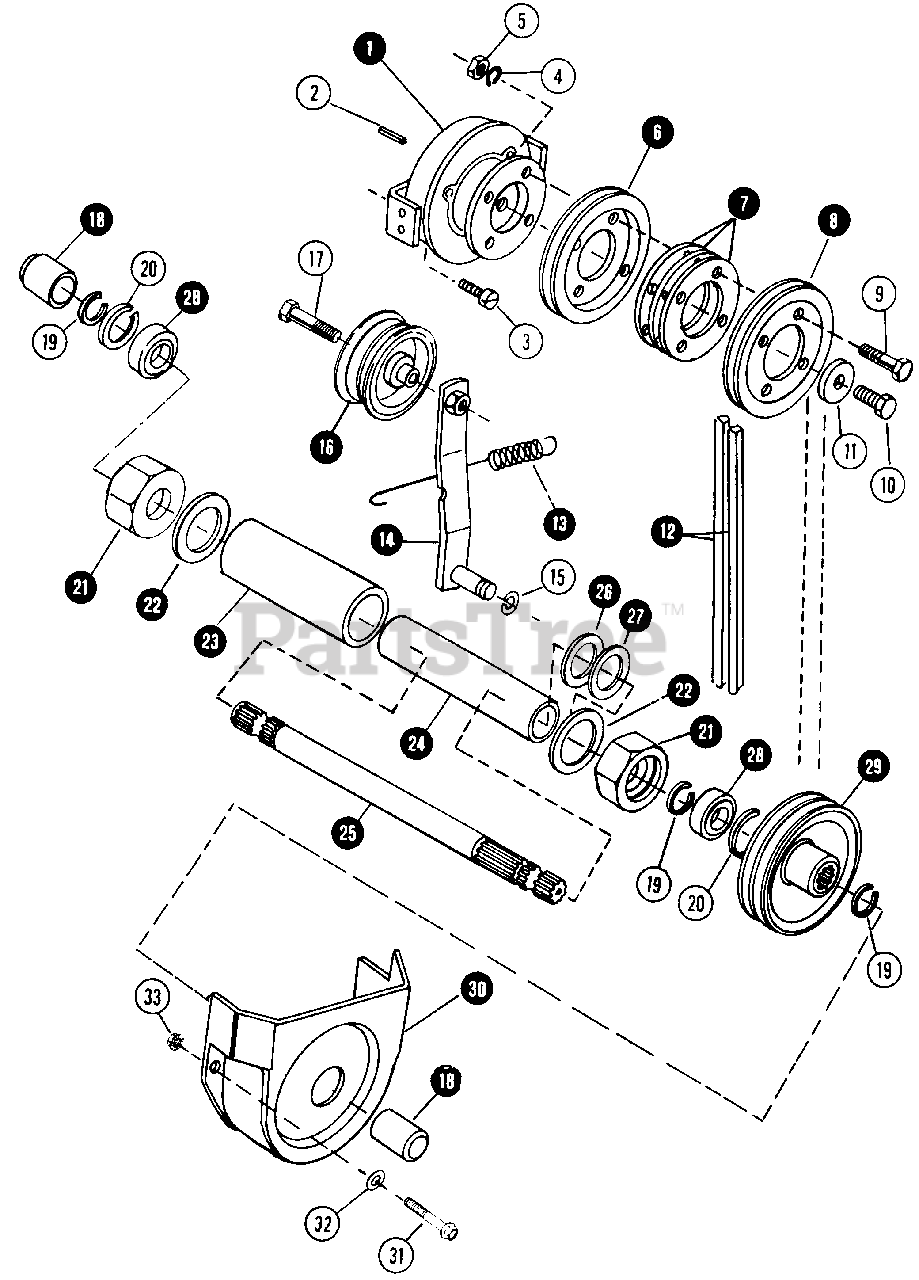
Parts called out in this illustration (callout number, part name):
1	CLUTCH, ELECTRIC - ASSEMBLY (Warner # 5208-752-010)(NLA)
2	KEY, CLUTCH TO CRANKSHAFT
3	SCREW, #10-32 x 1/2 FILLISTER HEAD SLOTTED (NLA, use 90955)
4	WASHER 1/4" LOCK
5	NUT, 1/4C HEX
6	PULLEY, CLUTCH DRIVER
7	SPACER, PULLEY
9	BOLT, 1/4C x 1-1/2 HEX HEAD
10	BOLT, 3/8C x 1-1/4 HEX HEAD
11	WASHER, CLUTCH RETAINER
12	V-BELTS, (MATCHED SET)
13	SPRING, IDLER PULLEY
14	ARM, IDLER
15	RING, IDLER ARM RETAINING
16	PULLEY IDLER, 3/8" ID, 4.0" OD, 1.25" Wide
17	BOLT, 3/8C x 1-3/4 HEX HEAD
18	CAP, MID P.T.O. VINYL
19	RING, RETAINING
20	RING, RETAINING
21	RETAINER, BEARING & AXLE SLEEVE
22	WASHER, FRONT AXLE THRUST
23	SPACER, AXLE PIVOT
24	SLEEVE, AXLE MOUNTING
25	SHAFT, MID POWER TAKE-OFF
26	SHIM, .030"
27	SHIM, .015"
28	BEARING, BALL, .98" ID, 2.04" OD, .59" Wide
29	PULLEY, P.T.O.
30	GUARD, BELT
31	BOLT, 3/8C x 1 HEX FLANGE
32	WASHER, 3/8" Flat
33	NUT, 3/8C HEX FLANGE
